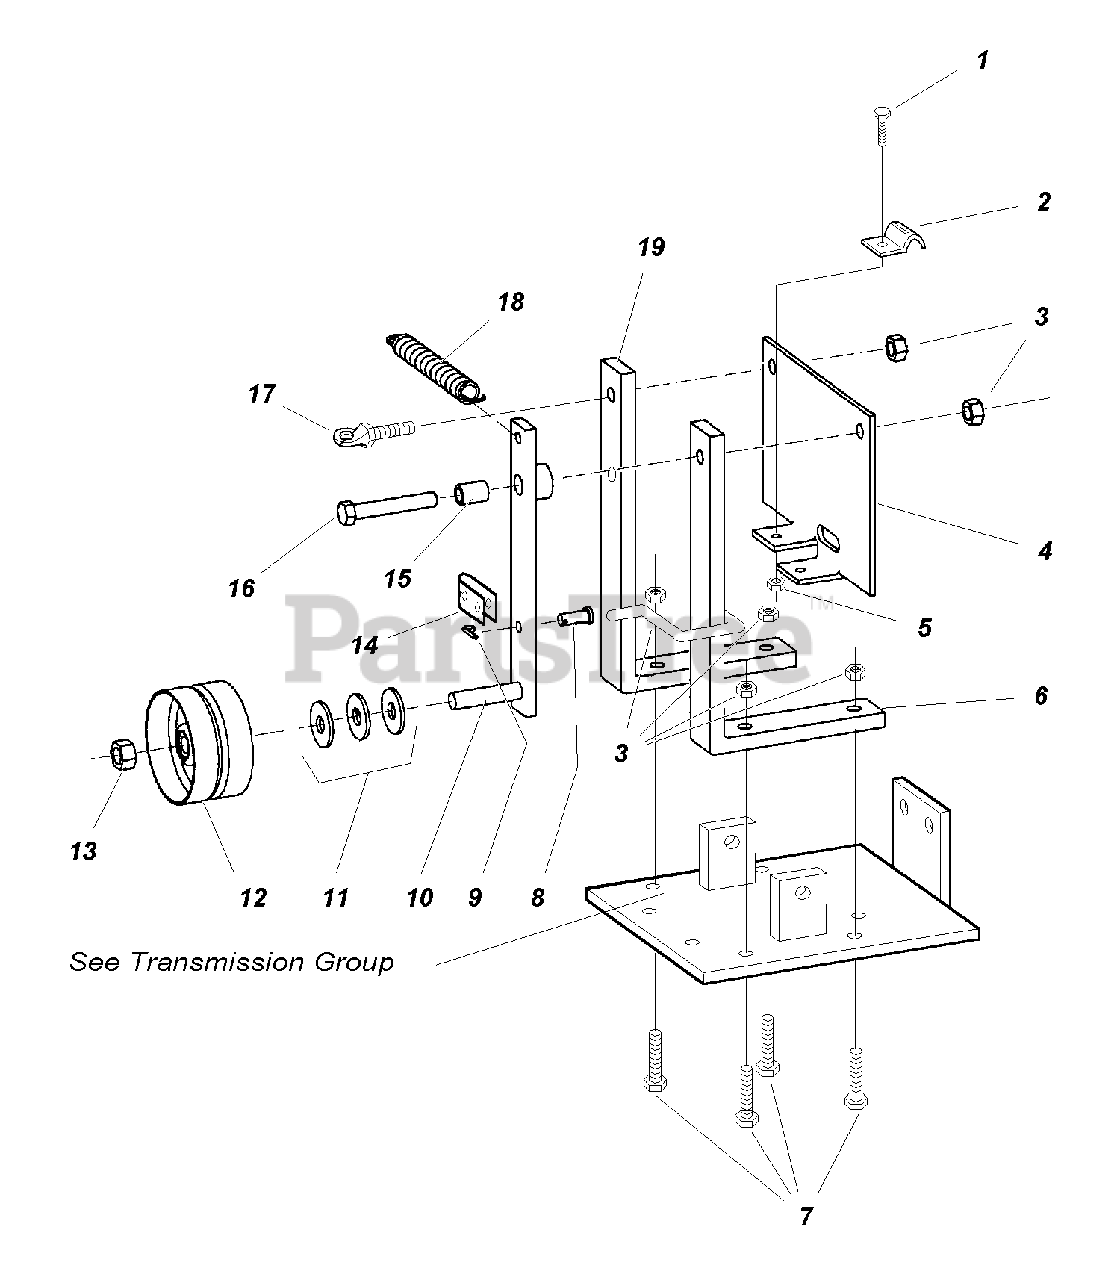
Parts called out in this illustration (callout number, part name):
1	CAPSCREW, 5MM x .8 x 16MM
3	NUT, Hex Flange Head, 5/16"-18 TWO, WAY Lock
4	BRACKET, Cable Mount
5	NUT, Hex Nylok
6	BRACKET, w/Forward Belt Guide
7	CAPSCREW, 5/16"-18 x 11/4" G5
8	PIN, Link Forward/Reverse
9	PIN, Cotter
10	ARM, Forward Idler
11	WASHER, 3/8"
12	PULLEY, Forward Idler
13	NUT, Hex Head, 3/8"-16
14	YOKE, Cable
15	BUSHING, Pivot 5/16"
16	CAPSCREW, Hex Head 5/16-18 x 2 G5
17	BOLT, Washer Head, 5/16"-18 x 1 1/4"
18	SPRING, Idler Arm
19	BAR, Shift Mounting
